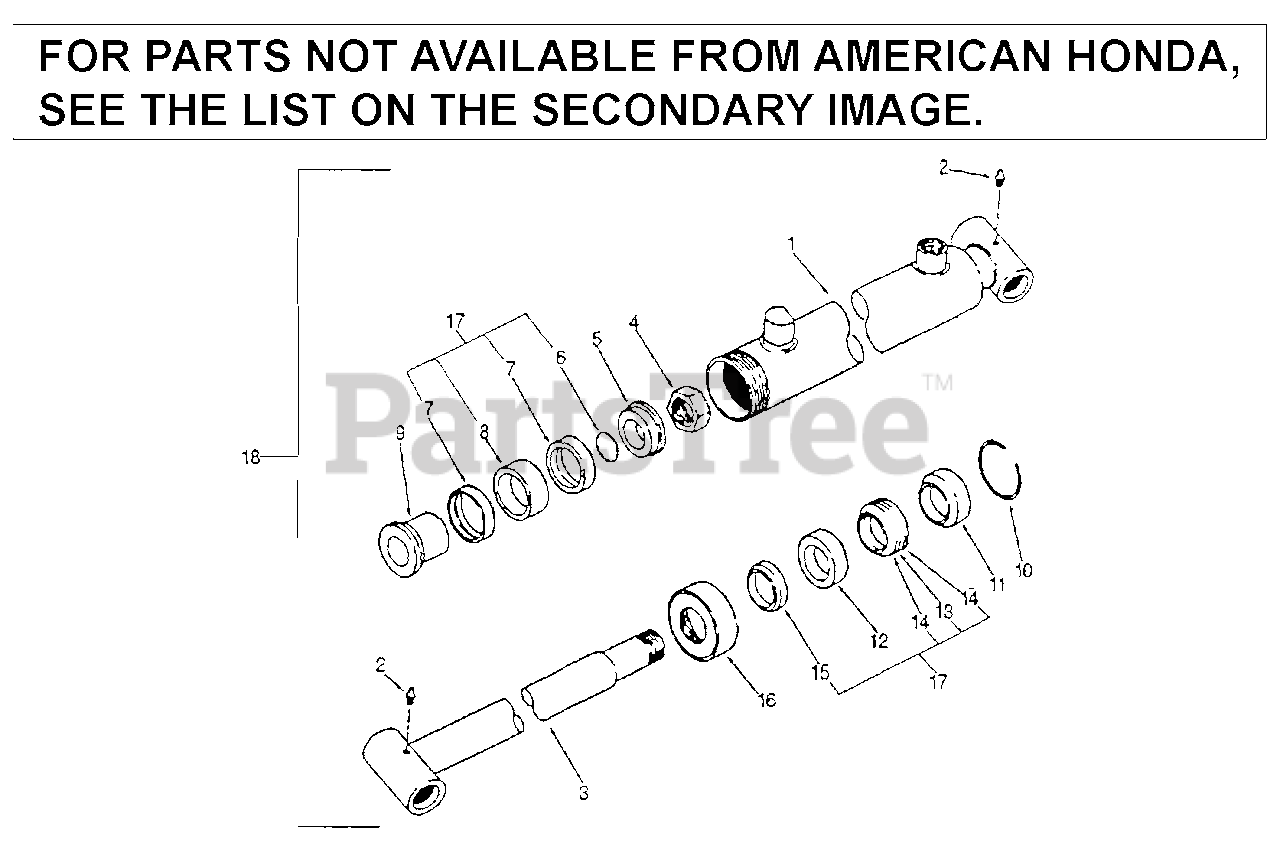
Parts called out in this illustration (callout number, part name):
1	BODY ASSY., BOOM CYLINDER
2	FITTING, GREASE
3	ROD ASSY., BOOM CYLINDER
4	LOCKNUT (3/4 - 16)
5	END, PISTON
9	PISTON, CYLINDER
10	WIRE, RETAINING
11	GUIDE, GASKET MALE
12	GUIDE, GASKET FEMALE
16	NUT, CARTRIDGE
17	SEAL KIT
18	CYLINDER ASSY., BOOM
